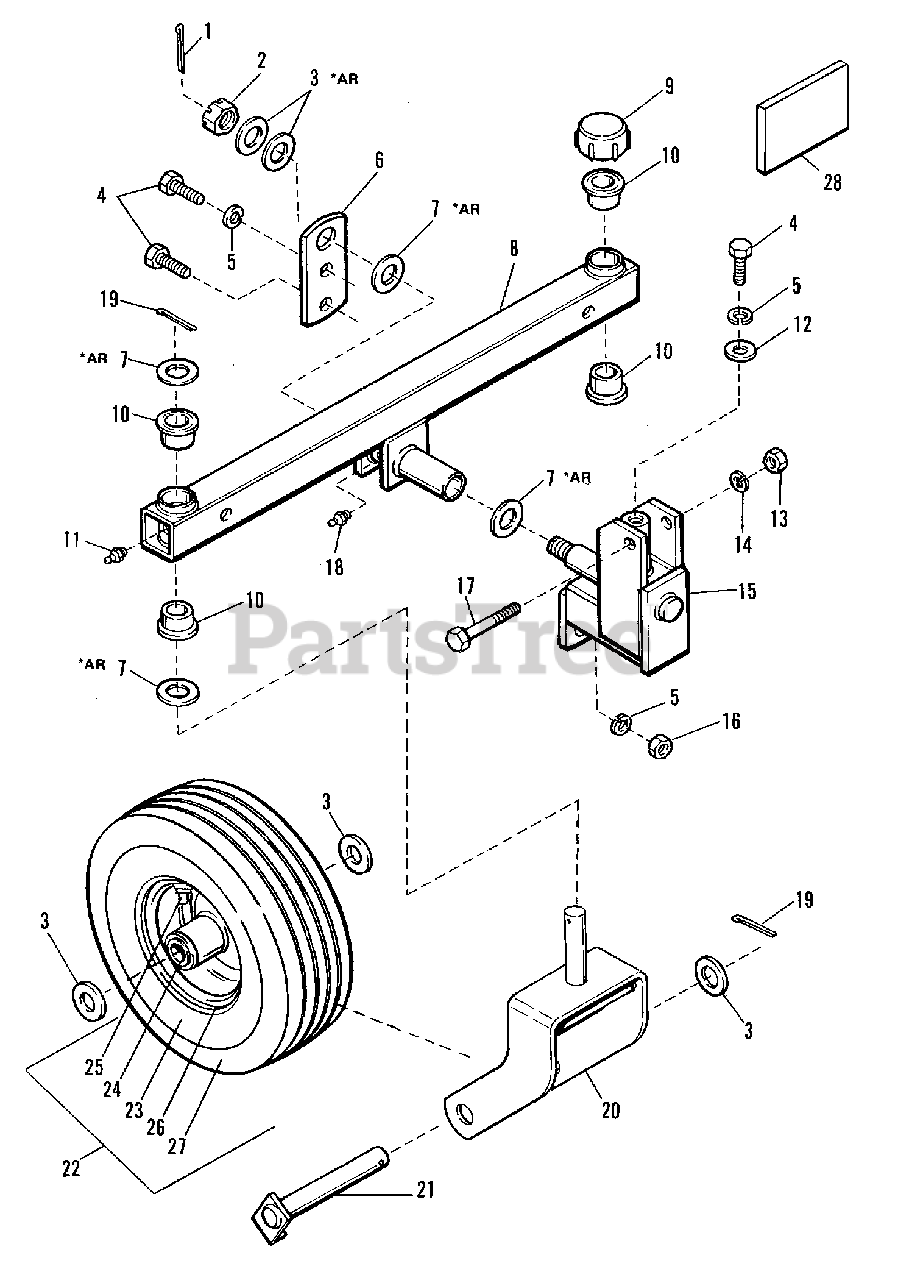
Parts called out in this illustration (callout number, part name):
1	PIN, Cotter
2	NUT, Castle
3	WASHER, 3/4" I.D. x 1" O.D.
4	CAPSCREW, Hex, 1/2-13 x 1-1/4
5	LOCKWASHER, Spring, 1/2
6	PLATE, Support
7	WASHER, 1" I.D. x 1-1/2" O.D.
8	AXLE ASSEMBLY
9	CAP, Plastic
11	FITTING, Grease
12	WASHER, 1/2" I.D. x 1-1/4" O.D.
13	NUT, Hex, 3/8-16
14	LOCKWASHER, 3/8
15	PIVOT SHAFT ASSEMBLY
16	NUT, Hex, 1/2-13
17	CAPSCREW, Hex, 3/8-16 x 3-1/2
18	FITTING, Grease
19	PIN, Cotter
20	CASTER ASSEMBLY
21	PIN AXLE ASSEMBLY
22	WHEEL & TIRE ASSEMBLY
24	BEARING, Flanged
25	VALVE STEM
26	WHEEL ASSEMBLY
27	TIRE
